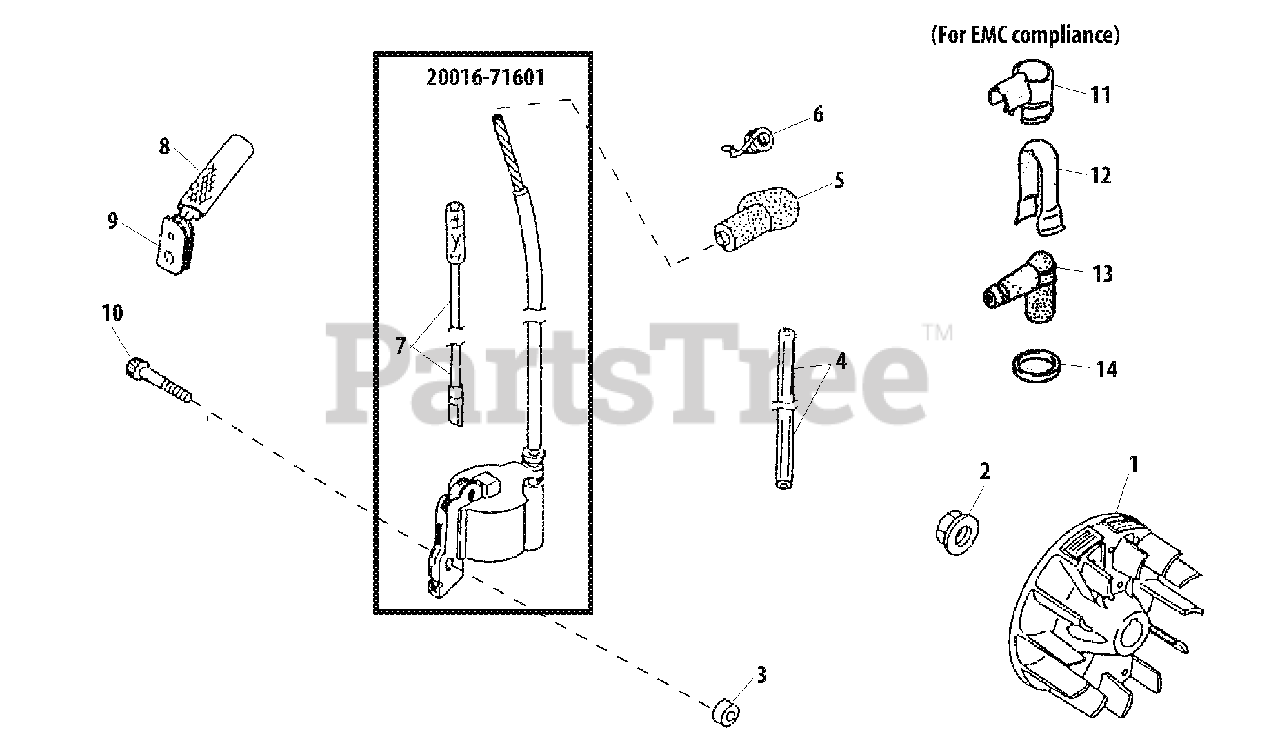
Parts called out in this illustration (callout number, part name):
1	FLYWHEEL
2	NUT M8
3	INSULATOR 4.2×11×6
4	TUBE, INSULATOR
5	CAP, SPARK PLUG
6	TERMINAL, SPARK PLUG
7	LEAD
8	TUBE, IGNITION COIL
9	GROMMET
10	BOLT M4×26
11	COVER, CAP
12	SHIELD
13	CAP, SPARK PLUG
14	SEAL, SPARK PLUG
20016-71601	COIL ASSY, IGNITION
